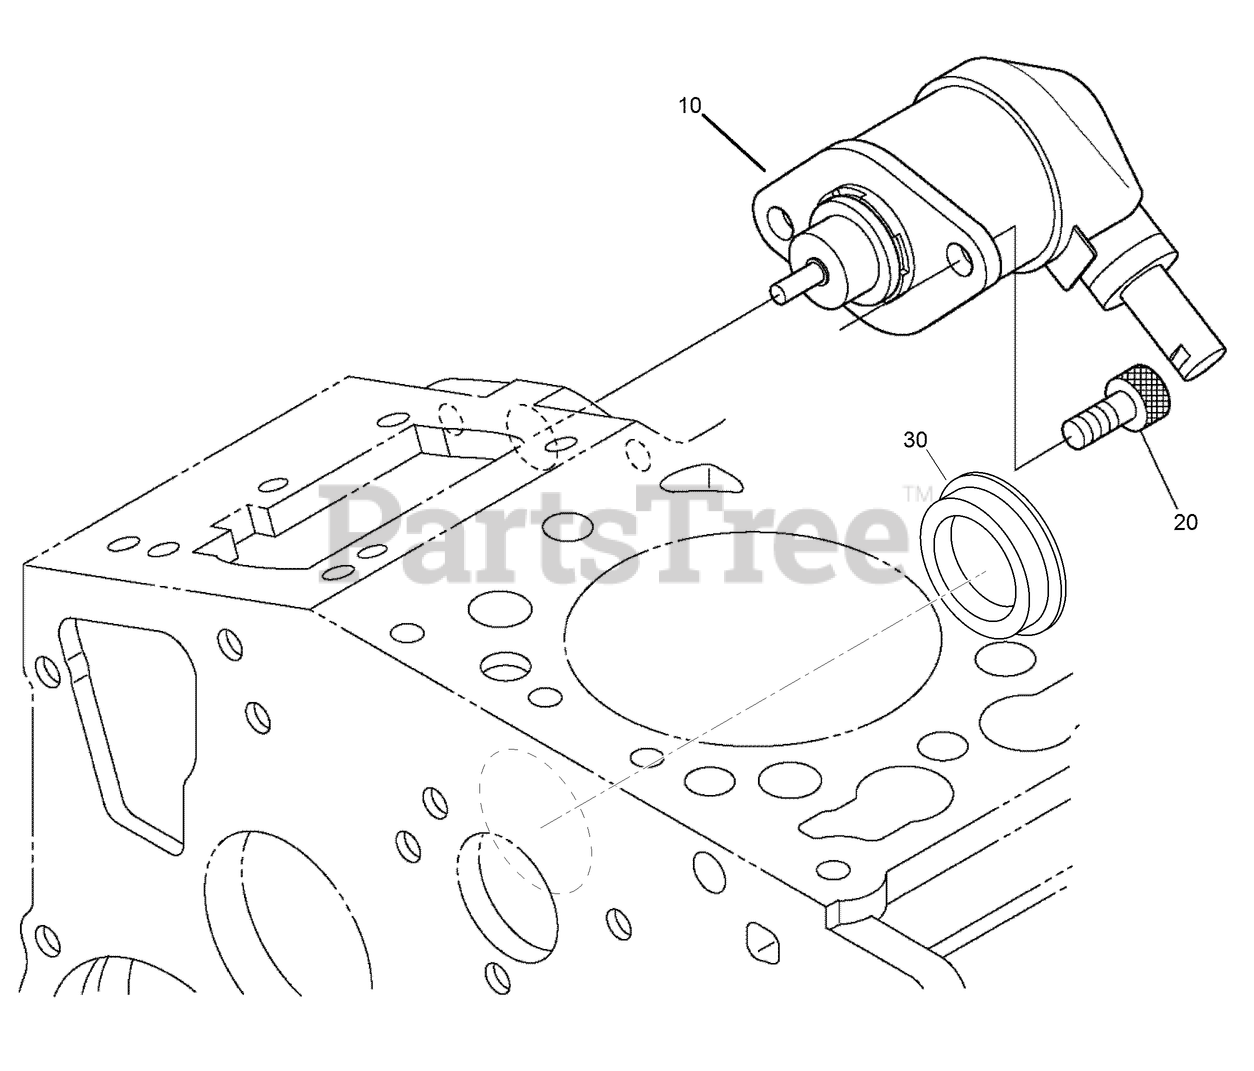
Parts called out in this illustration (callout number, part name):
10	SOLENOID-STOP
20	SCREW-HSH
30	COVER-PUMP
